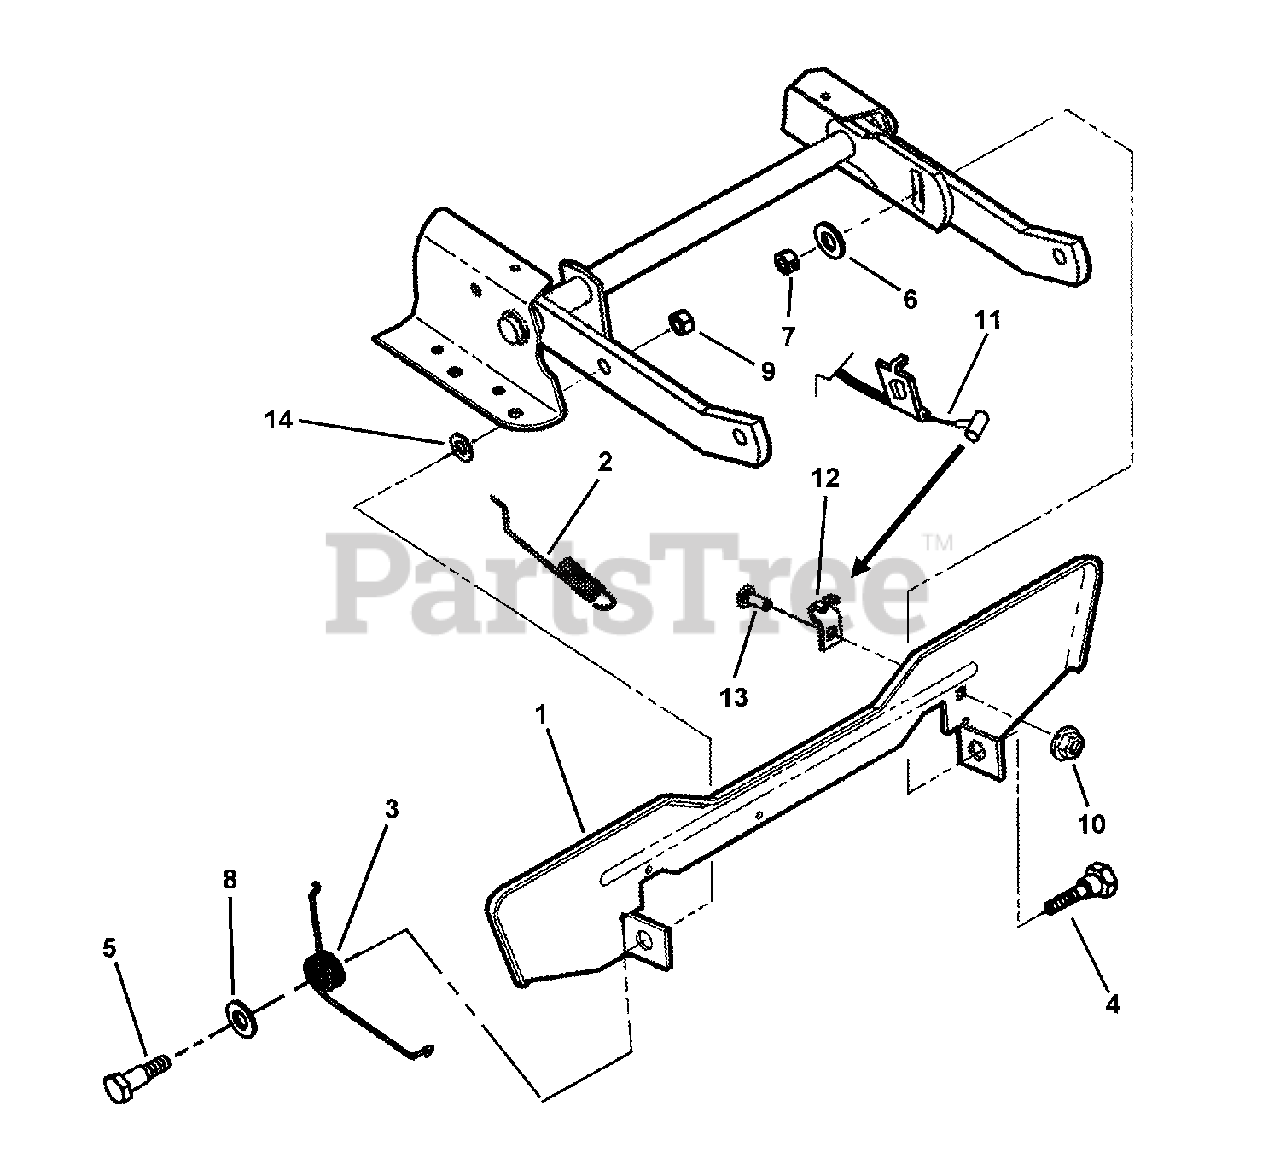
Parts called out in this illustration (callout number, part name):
1	FOOT PEDAL, Blade Stop Control
2	SPRING, Latching (.072 dia.)
3	SPRING, Pedal
4	SHOULDER BOLT, 3/8-24 w/Nylon Patch, GR 5
5	SHOULDER BOLT, 3/8-24 x 9/16"
6	WASHER, Flat 13/32" ID x 1.25" x 1/8" Thick ZP
7	NUT, 3/8-24 Hex, GR B
8	WASHER, 1/2" Flat SAE
9	NUT, 3/8-24 Hex Center Lock
10	NUT, 1/4-20 Hex Flange Lock, GR 5
11	CABLE ASSEMBLY, No Mow in Reverse
12	CLIP, Cable
13	BOLT, 1/4-20 x 3/4" Square Neck Carriage, GR 5
14	WASHER, 3/8" Flat SAE
